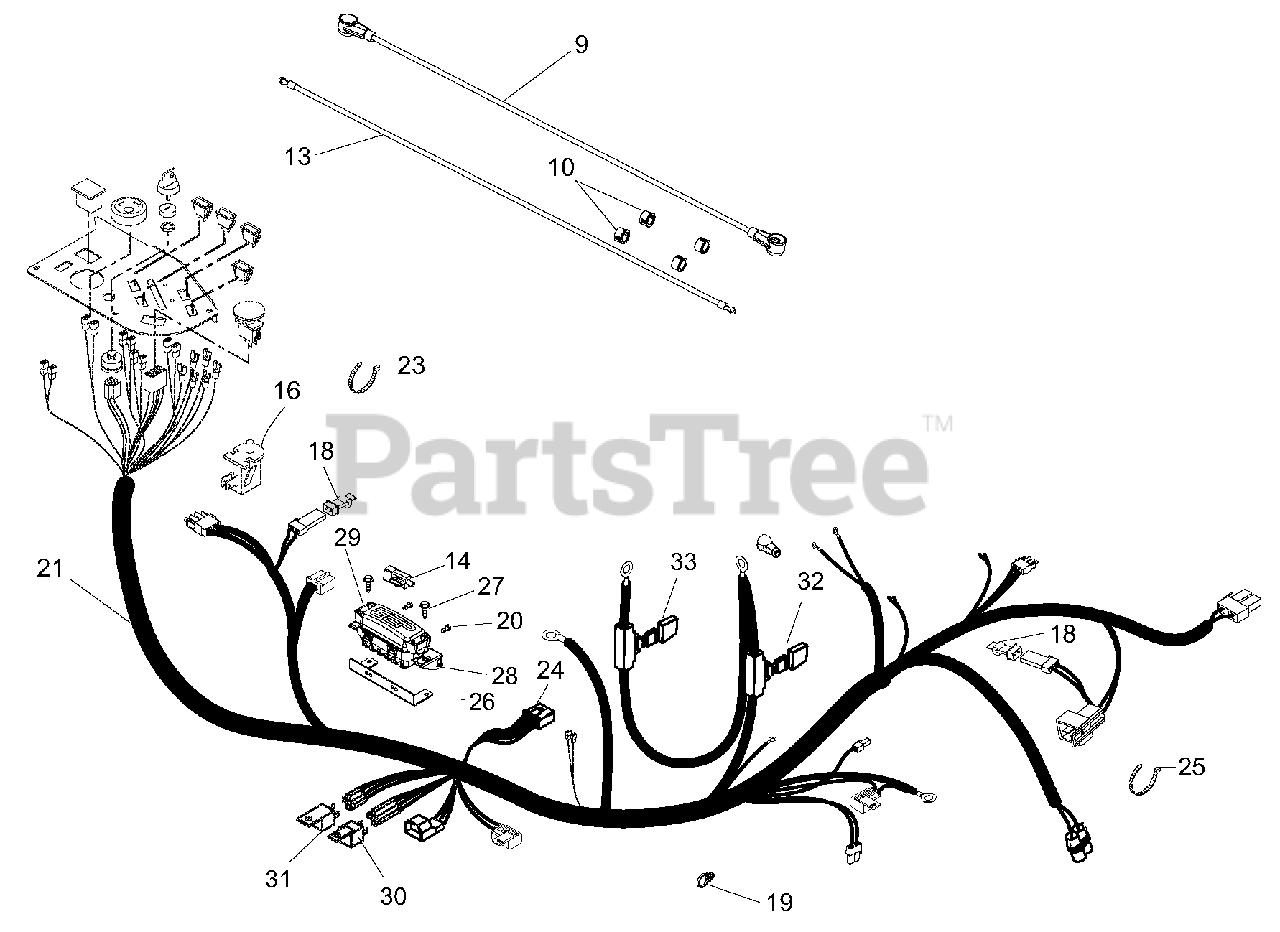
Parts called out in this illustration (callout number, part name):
9	Cable, POS Battery w/Boots 4 x 48
10	Bushing, Panel Snap .687 x .875 x .56
13	Cable, Negative Battery 49.0"
14	Switch, Snap-In - N.O./N.O.
16	Switch, Snap Mounting (Included with Seat)
18	Diode, Connector Shell (Included with Harness)
19	Cable Tie with TREE (.25 HOLE)
20	Bolt, Hex M6-1.0X25
21	Harness, PT400 Diesel Wiring
23	Cable Tie
24	Module,Interlock,Delay (included with Harness)
25	Cable Tie
26	Fuse Holder Mounting Bracket
27	Screw-Tapping .25-20X.50 Hex Washer Head
29	Cover, Fuse Holder
30	Relay, 70A (included with Harness)
31	Relay, Sealed w/Diode (included with Harness)
32	Fuse, 40A Slow-Burn Maxi (included with Harness)
33	Fuse, 70A MAXI
34	Glow Plug Timer Module (included w/engine)
